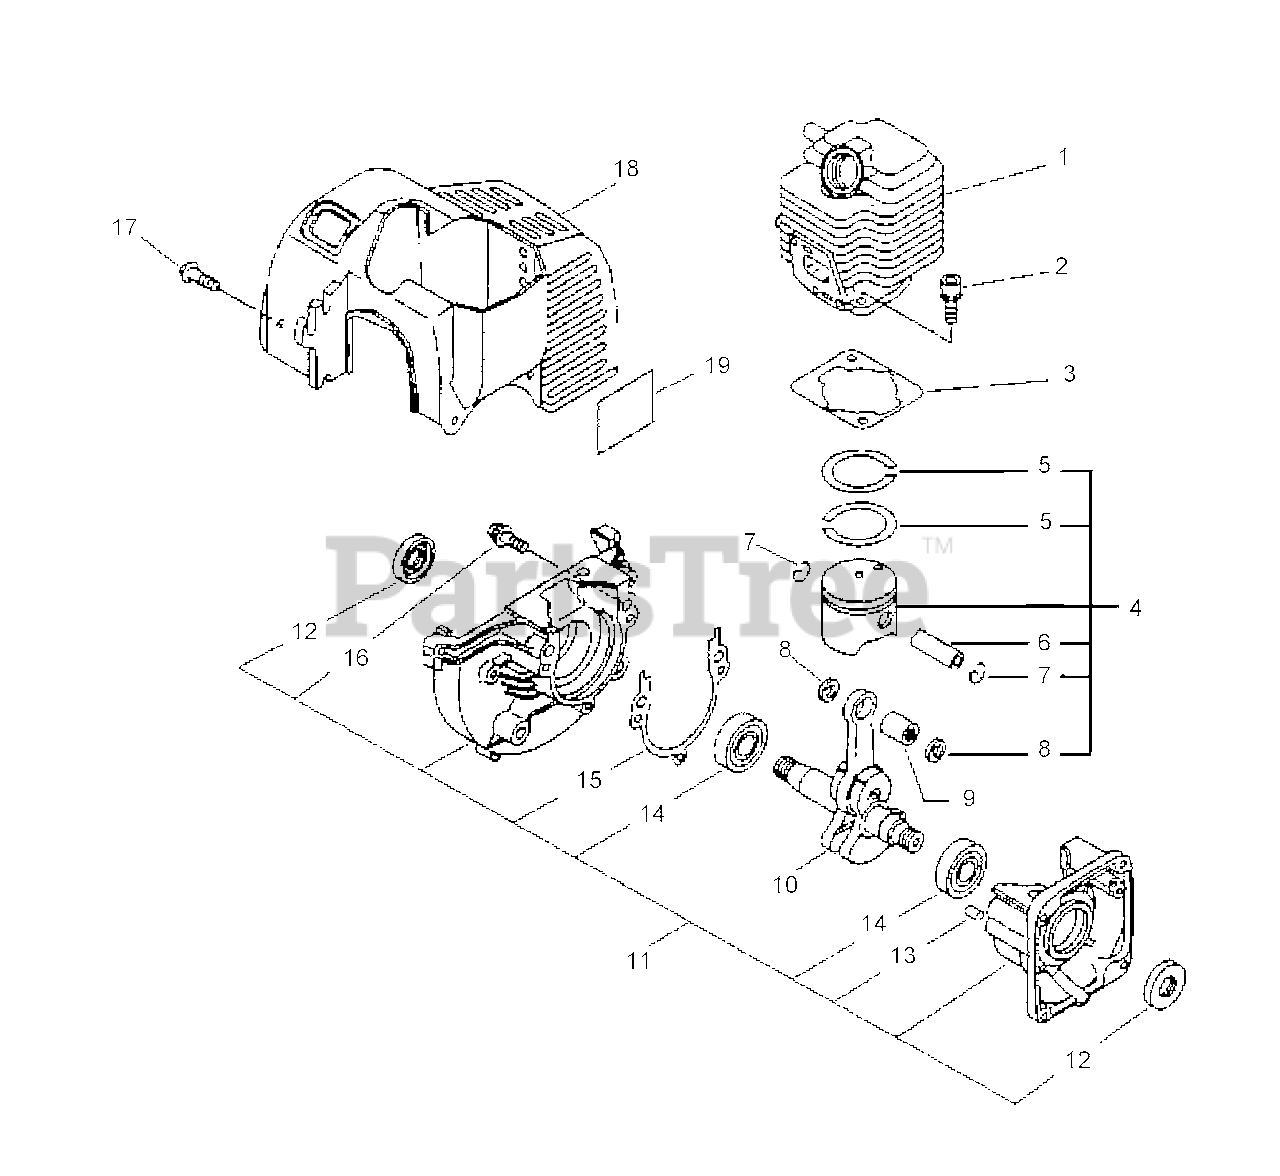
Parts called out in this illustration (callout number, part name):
1	CYLINDER
2	SCREW - 5X22
3	GASKET, CYLINDER
4	PISTON KIT
5	RING, PISTON
6	PIN, PISTON
7	RING, RETAINING
8	SPACER, PISTON
9	BEARING, NEEDLE
10	CRANKSHAFT ASSY
11	CRANKCASE KIT
12	SEAL, OIL
13	PIN - LOCATING
14	BEARING, BALL - 6201
15	GASKET, CRANKCASE
16	SCREW - 5X28
17	SCREW - 4X12
18	COVER, ENGINE - GRAY
19	LABEL - MODEL
